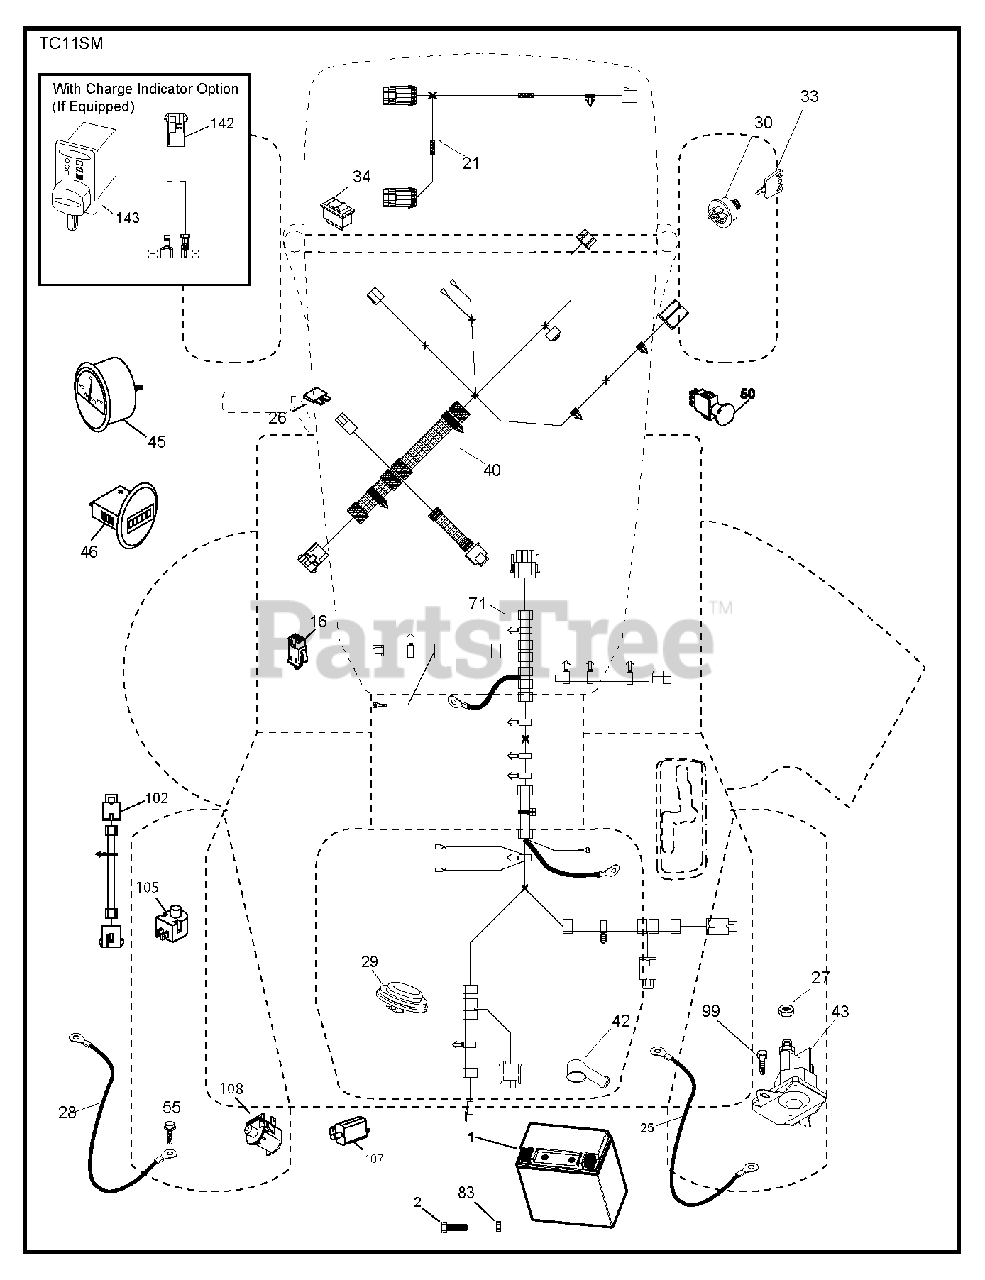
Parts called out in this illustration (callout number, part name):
1	BATTERY BATTERY 14AH 12V LEOC
2	SCREW.HEX.HEAD.CAP.M6 X1.12W
16	SWITCH INTERLOOK PUSH-IN
21	HARNESS LIGHT ASSY TRACTOR,
25	CABLE.BATT.8GA.RED9.C
26	FUSE 20AMP
27	NUT
28	CABLE.BATT.BLCK10.SLV
29	SWITCH.SEAT.DELTA.OPC.
30	SWITCH.IGN.DELTA.W.LGH.ROS
33	KEY.CHAIN.BLISTER.PACK.GEN.INT
40	HARNESS.DASH.TCRD.EL.RND.CH.RS
42	TERMINAL COVER
43	SOLENOID.STARTER.BRASS.PLUNGER
45	GAUGE.AMMETER.SILVER/WHITE
46	GAUGE.HOUR.METER.SILVER/WHITE
50	SWITCH.PTO.8TERMINAL.STD.BLK
55	SCREW 5/16"
71	HARNESS
83	NUT NUT SQUARE
99	SCREW HEXWSHR 1/4-20X3/4
102	HARNESS ASSY
105	REVERSE SWITCH
107	.WITCH.FULL BAGGER.INDICATOR
108	SWITCH.SNAPMOUNT.NC
142	CHARGE.PORT.PIGTAIL HARNESS
143	CHARGE.PORT
